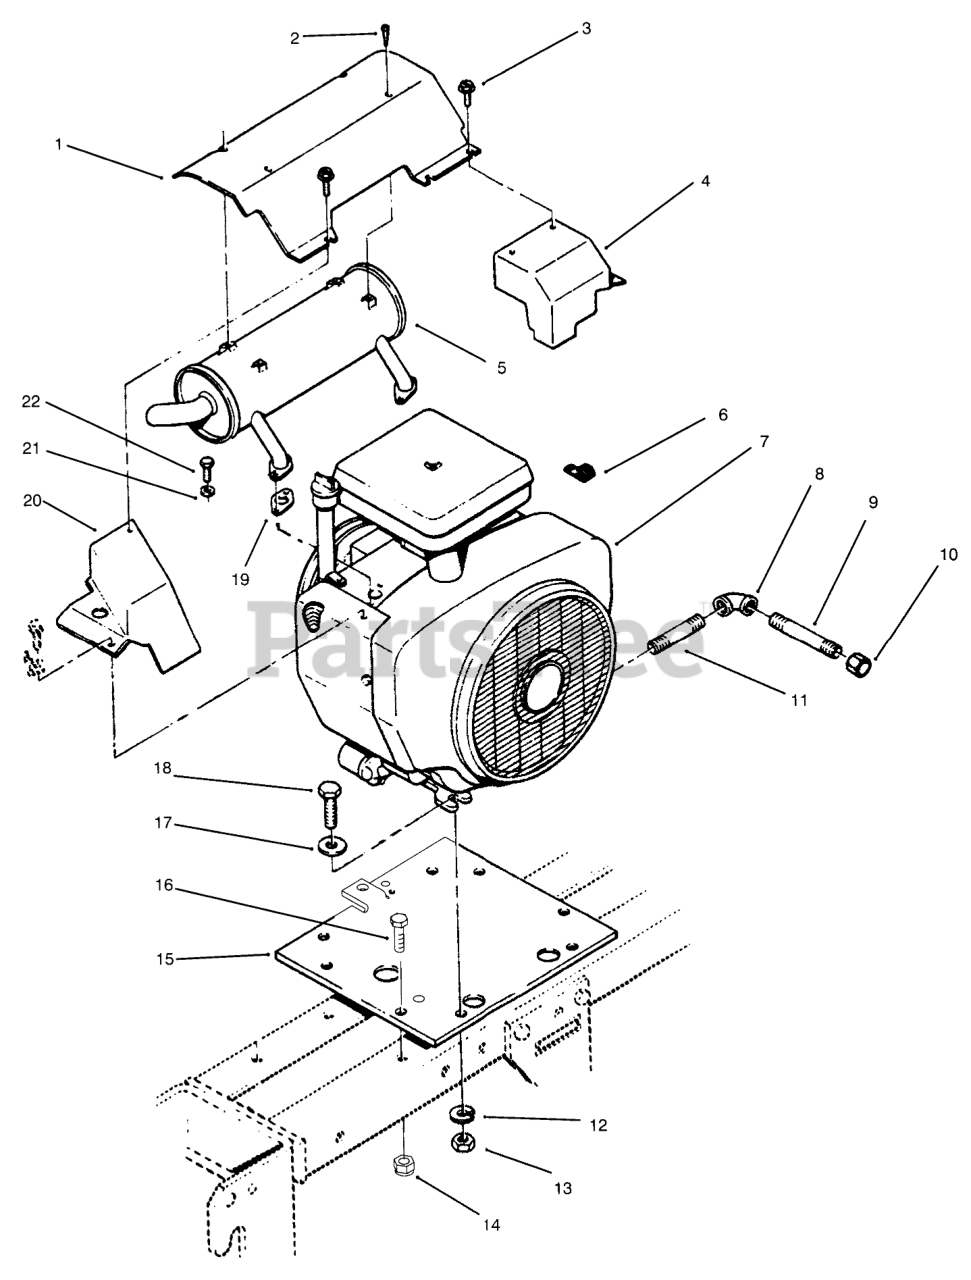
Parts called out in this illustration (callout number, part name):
1	Air Deflector
2	Screw
3	SCREW
4	RH Exhaust Cover
5	MUFFLER-EXHAUST
6	CLIP
7	Engine-20HP
8	ELBOW 3/8 90 DEG
9	PIPE-NIPPLE 3/8 X 4"
10	Cap
11	Pipe
12	WASHER-LOCK
13	NUT-HEX
14	NUT-LOCK, NI
15	PLATE-ENGINE B
16	SCREW-HH
17	WASHER-FLAT
18	SCREW-HH
19	Gasket-Exhaust
20	LH Exhaust Cover
21	WASHER-LOCK
22	SCREW-HH
